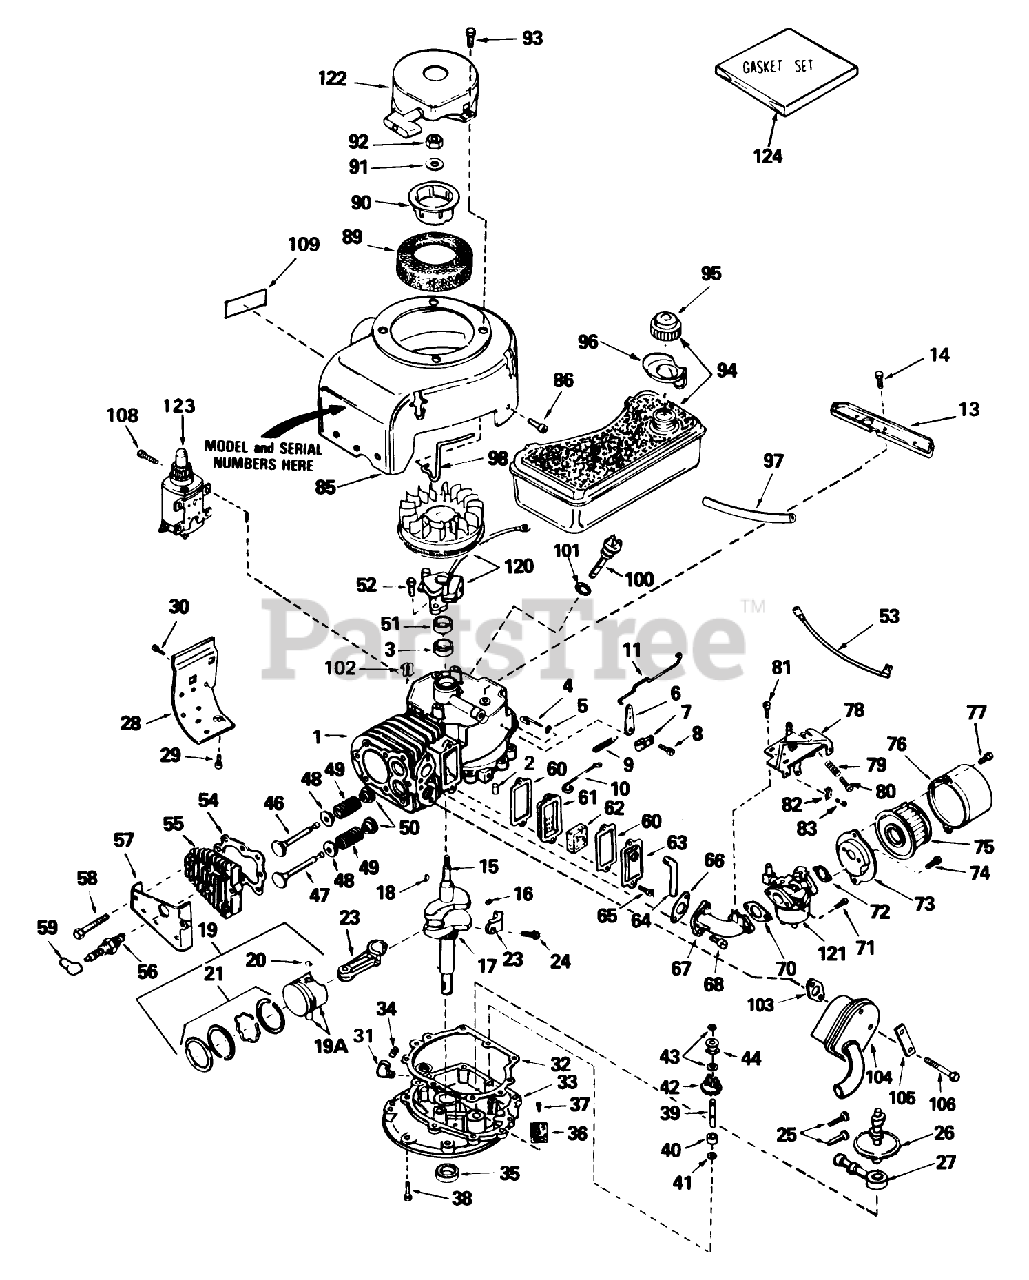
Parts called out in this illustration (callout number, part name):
1	Cylinder Assy. (Incl. Nos. 2, 4 44)
2	Pin-Dowel
3	Oil Seal
4	Rod, Governor (Incl. Nos. 146)
5	Washer-Flat
6	Lever-Governor
7	Clamp-Lever, Governor
8	Screw
9	Spring Governor
10	Link Governor Spring
11	Link Governor
13	Bracket-Blower Housing
14	Screw (1/4-20x19/32)
15	Crankshaft Assembly (Incl. Ref. #16 17)
16	Pin, Groove
17	Gear-Crankshaft
18	Key-Flywheel
19	Piston, Pin Ring Assy. (Std.) (Incl. Ref. #19A, 20 21)
19	Piston, Pin Ring Assy. (.010 oversize) (Incl. Ref. #19A, 20 21 )
19	Piston, Pin Ring Assy. (.020 oversize) (Incl. Ref. #19A, 20 21)
19A	Piston Pin Assy. (Std.) (Incl. Ref. #20)
19A	Piston Pin Assy. (.010 oversize) (Incl. Ref. #20)
19A	Piston Pin Assy-. (.020 oversize) (Incl. Ref. #20)
21	ORing
21	Ring Set (.010" OS)
21	Ring Set (.020" OS)
23	Rod Assy., Connecting (Incl. Nos. 10 18)
24	Bolt, Connecting Rod
25	Lifter-Valve
26	Screw
27	Pump, Oil
28	Emnsion, Blower Housing
29	Screw
30	Screw
31	Elbow, 90
32	Gasket-Cover, Cylinder
33	Flange Assy., Mounting (Incl. Ref. #34 thru 37 39)
34	Plug-Drain, Oil (SQH 1/4-18)
35	Seal-Oil
36	Screen-Oil Filter
37	Screw
38	Screw (1/4-20 x 1-1/4)
39	Shaft, Governor
40	Spacer Assy. Governor (Incl. Ref. #41)
41	Washer-Flat
42	Governor Gear ASM
43	Ring-Retaining
44	Spool-Governor
46	Valve, Intake (Standard)(Incl. No. 9)
46	Valve, Intake (1/32" oversize)(Incl. No. 9)
47	Valve, Exhaust (Standard)(Incl. No. 9)
47	Valve, Exhaust (1/32" oversize)(Incl. No. 9)
48	Cap-Spring, Valve
49	Spring-Valve
50	Keeper-Spring, Valve
51	Gasket Stator
52	Screw
53	SPOOL RETAINER (10-PK)
54	Gasket-Cylinder Head
55	CYLINDER HEAD
56	Plug, Spark (J17LM or equiv.)
56	Plug, Spark (Champion RCJ-8)
57	Cover-Head, Cylinder
58	Screw (5/16-18 X 2-1/2)
59	Cover-Spark Plug
60	Gasket-Breather
61	Body-Breather
62	Element-Breather
63	Cover-Valve
64	Tube-Breather
65	Screw
66	Gasket-Intake
67	Pipe-Intake
68	Screw (T-30, 5/16-18x1-3/32)
70	Gasket
71	Screw-Hex Hd.
72	Gasket
73	Bracket
74	Screw (10-32 x 1/2)
75	Element
76	Body-Air Cleaner
77	Screw
78	Control Assy.Speed (Incl. Ref. #79 80)
79	Spring-Compression
80	Screw
81	Screw (10-24 x 9/16)
82	Conduit
83	Screw (10-32 x 3/8)
85	Housing Blower
86	Screw, Hex Hd.
89	Screen, Air
90	Cup-Starter
91	Washer-Belleville
93	Screw
94	Tank Assy., Fuel (Incl. No. 127)
95	Cap-Fuel
96	Deflector-Fuel
97	Line-Fuel (8.62)
98	Clamp, Tank Holdown
100	Dipstick, Oil (Incl. No. 45)
101	Gasket
102	51004 GIL ROTARY TI
103	Gasket Exhaust
104	Muffler
105	62513 SNWTHWR W/284
106	Screw Hex Hd.
108	Screw
109	Decal, Instruction
120	Magneto(The complete magneto is not available as an assembly. The magneto number is shown for reference purposes only. Order component parts individually,as shown in parts list.)
121	Carburetor
122	Starter, Rewind
123	Tine Shaft
124	Gasket Set
